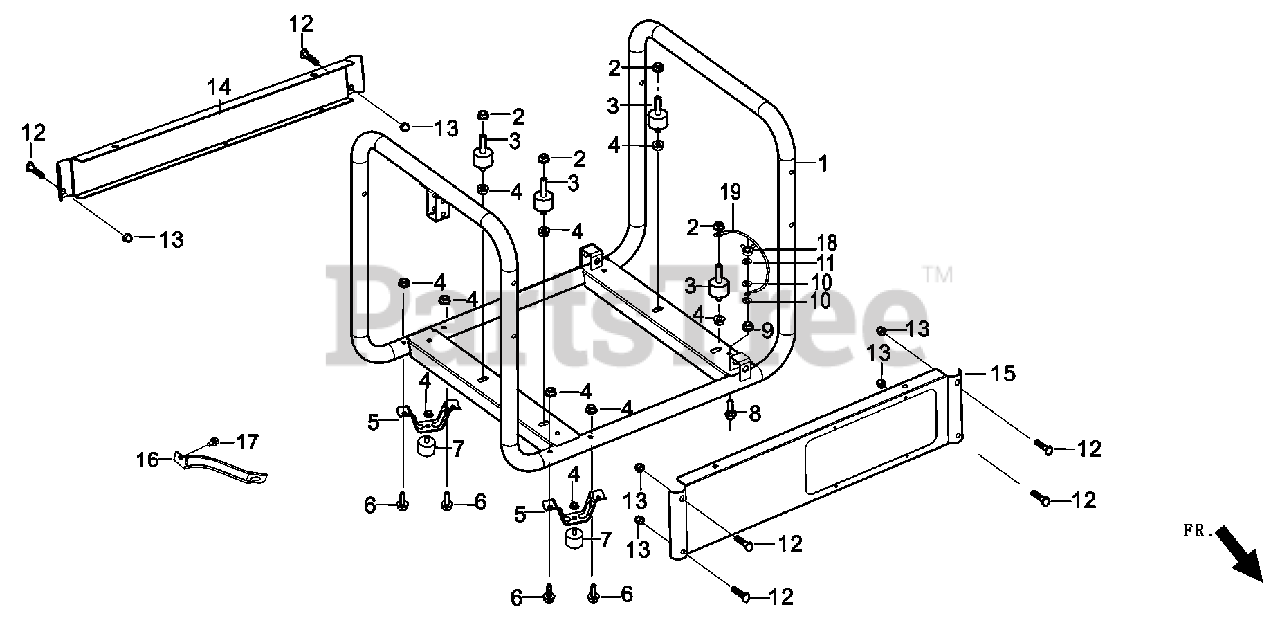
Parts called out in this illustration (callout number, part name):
1	ASSEMBLY FRAME GP PS
3	VIB MNT 25.5 X 36.0 X M8/M10
4	NUT
5	FRAME FOOT GP5-7.5KW
7	VIB MNT 38.1 X 25.4 X M8-1.25
10	WASHER FLAT
11	SPRING WASHER
14	PANEL RAIL BACK GP
15	PANEL RAIL CPNL SIDE GP
16	SUPPORT AIR CLEANER
19	EARTHING LUG
